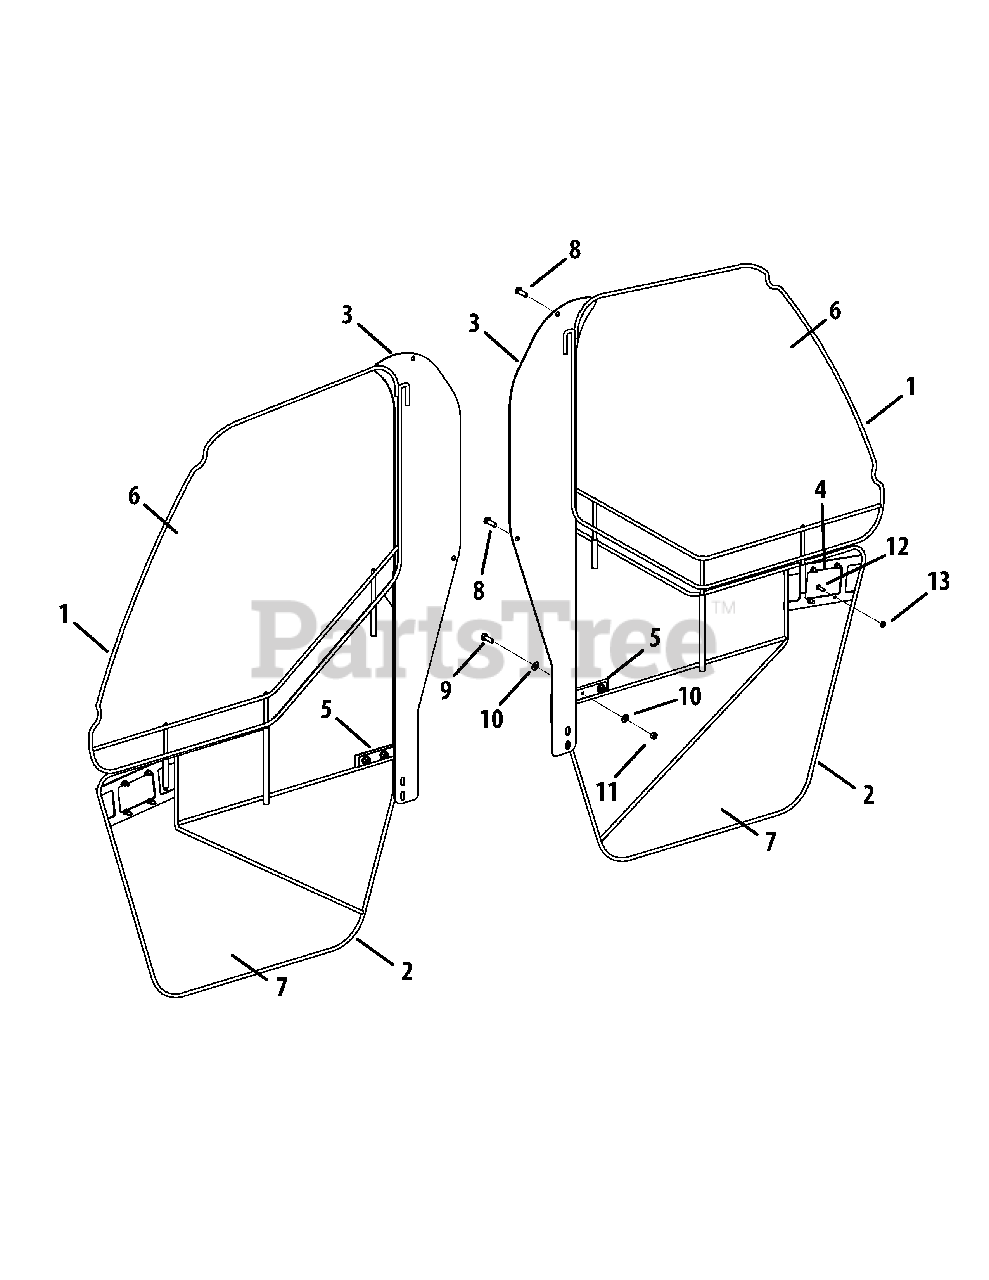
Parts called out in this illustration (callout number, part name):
1	Door, Upper, Driver Side
1	Door, Upper, Passenger Side
2	Door, Lower, Driver Side
2	Door, Lower, Passenger Side
3	Door Mount Plate, Driver Side
3	Door Mount Plate, Passenger Side
4	Door Latch Mechanism, Passgr. Sd.
4	Door Latch Mechanism, Driver Sd.
5	Lower Hinge, Adjust., Driver Side
5	Lower Hinge, Adjust., Pass. Side
6	Door Skin Upper, Driver Side
6	Door Skin Upper, Passenger Side
7	Door Skin Lower, Driver Side
7	Door Skin Lower, Passenger Side
8	Hex Cap Screw, 3/8-16 x 3.0
9	Hex Cap Screw, 3/8-16 x 1.0
10	Flat Washer, .394 x .786 x .060
11	Nut, Lock, 3/8-16
12	Screw, #10-24 x .5
13	Nut, Lock, #10-24
